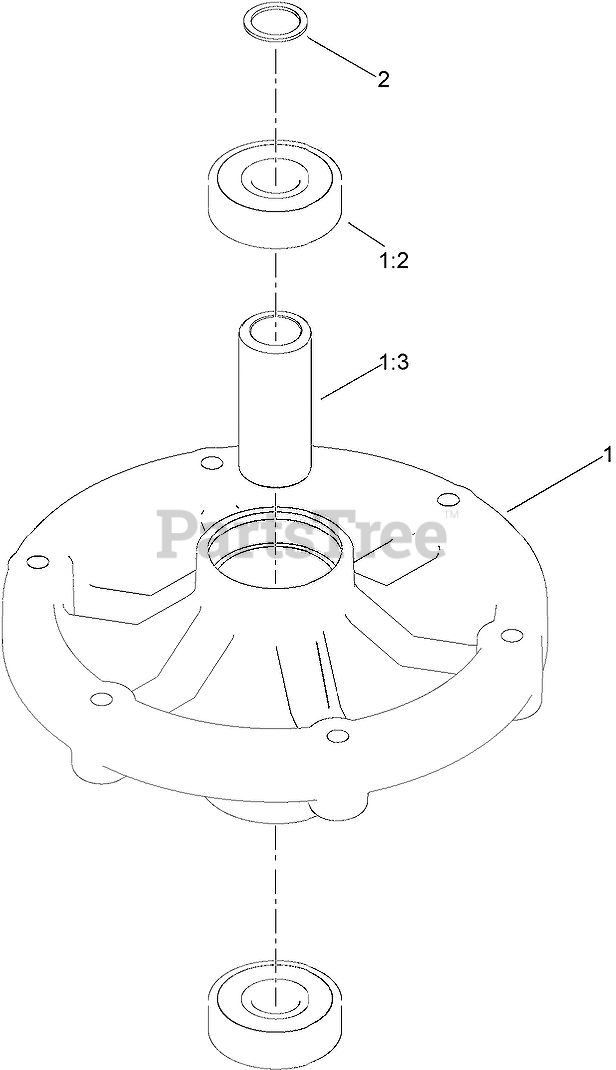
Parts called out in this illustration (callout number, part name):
1	HOUSING-CUTTER
1:2	BEARING
1:3	SPACER-BEARING
2	WASHER-THRUST
